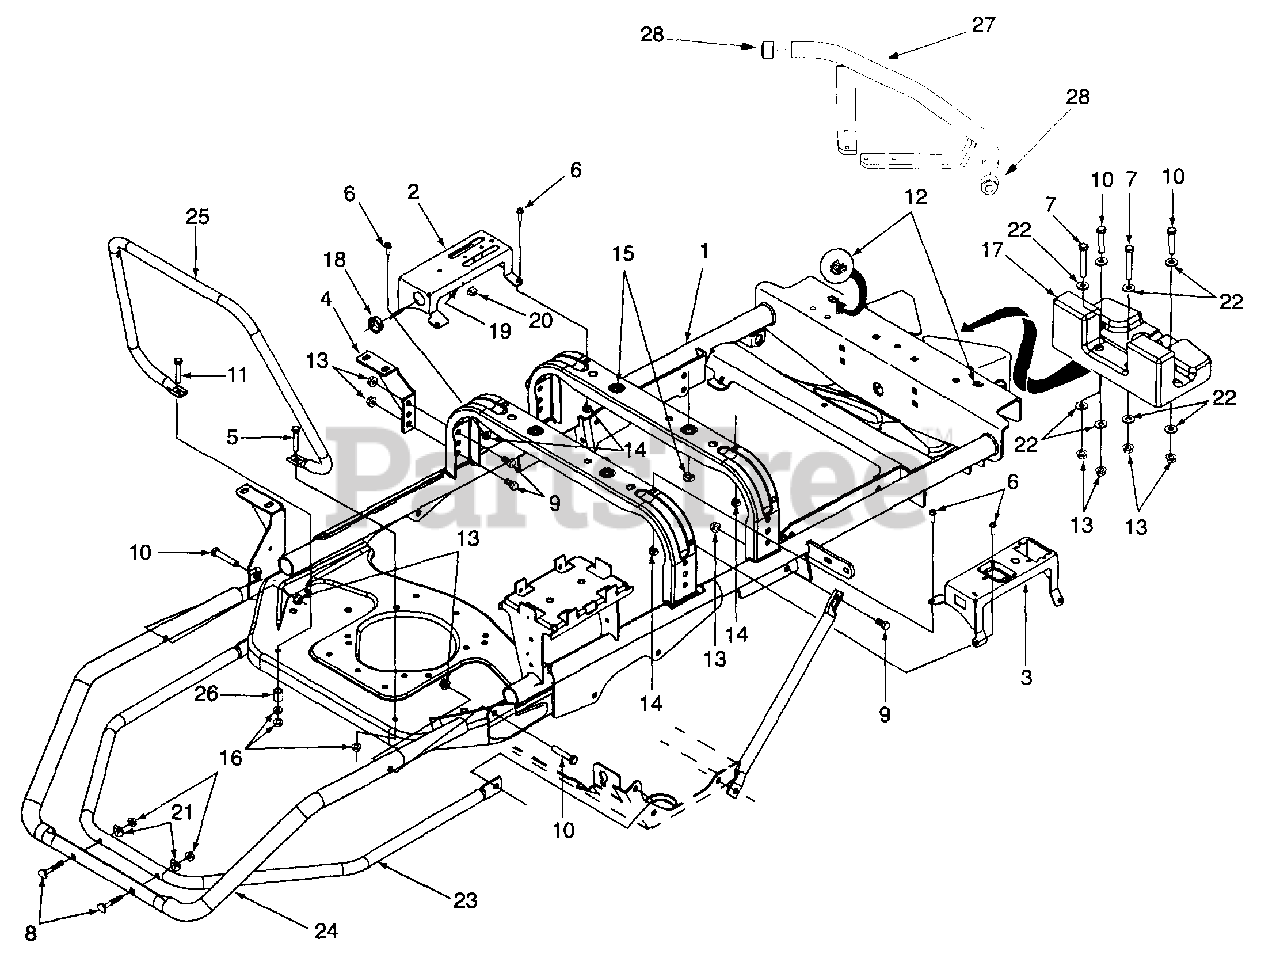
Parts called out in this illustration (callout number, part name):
6	Screw, Hex Wash. Hd. Tapp, 1/4-20 x .625
7	Screw, Hex Cap, 3/8-16 x 2.5 GR5
8	Screw, Curved Hd. Carriage, 5/16-18 x 2.0
9	Screw, Hex Cap, 3/8-16 x 3/4 GR5
10	Screw, Hex Cap 3/8-16 x 2.0 GR5
11	Screw, Hex Cap 5/16-18 x 1.75 GR5
12	Nut, Retainer, 3/8-16
13	Nut, Hex Flange Lock, 3/8-16
14	Nut, Retainer, 1/4-20
15	Nut, Retainer, 3/8-16
16	Nut, Hex Flange Lock, 5/16-18 GR5
19	Rivet, Pop, .125
20	Clip, Spring
21	Washer, Saddle
22	Washer, Flat, .406 x .875 x .105
